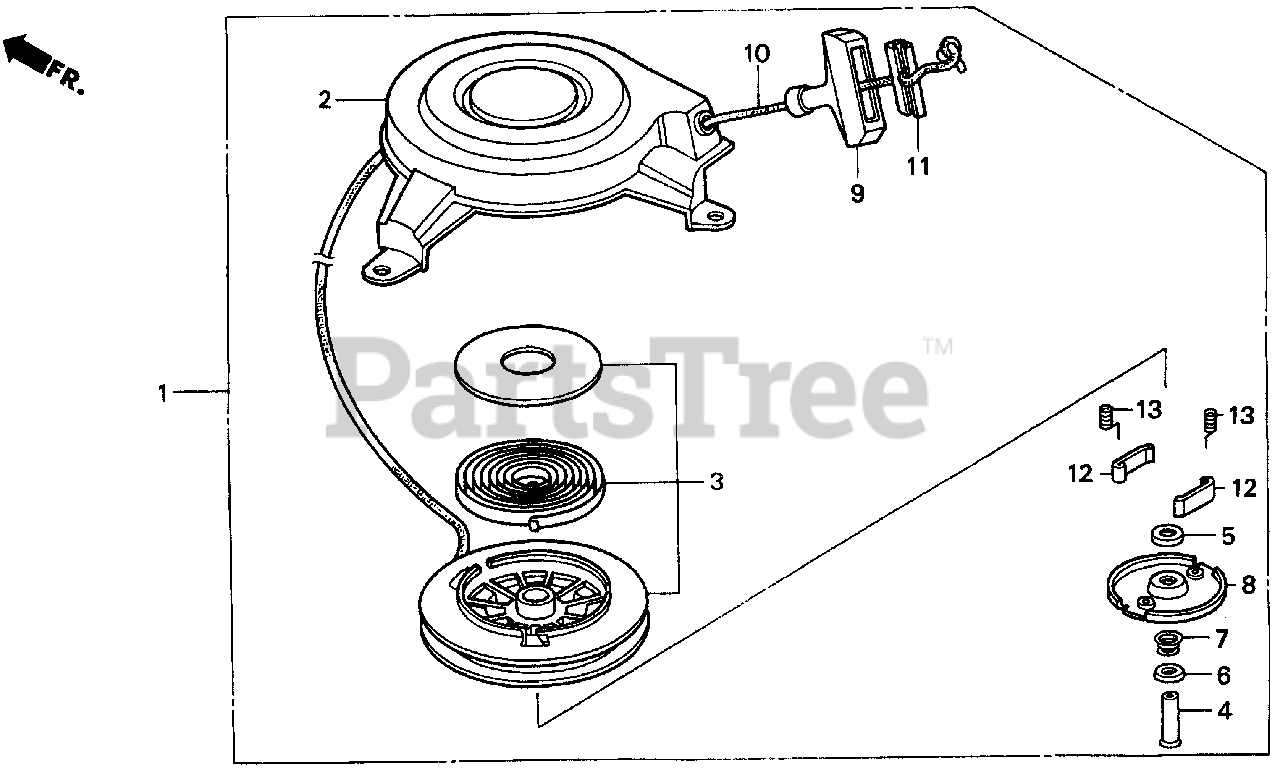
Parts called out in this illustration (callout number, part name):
1	STARTER ASSY., RECOIL
2	HOUSING ASSY. (NA USE ALT:28400-ZG9-803)
3	PULLEY & SPRING ASSY.
4	PIN, CENTER
5	PLATE A, FRICTION
6	PLATE B, FRICTION (NOT AVAILABLE)
7	SPRING, FRICTION
10	ROPE, RECOIL STARTER (#4X85")
11	HANDLE, REINFORCEMENT
12	RATCHET, STARTER
13	SPRING, DOG
